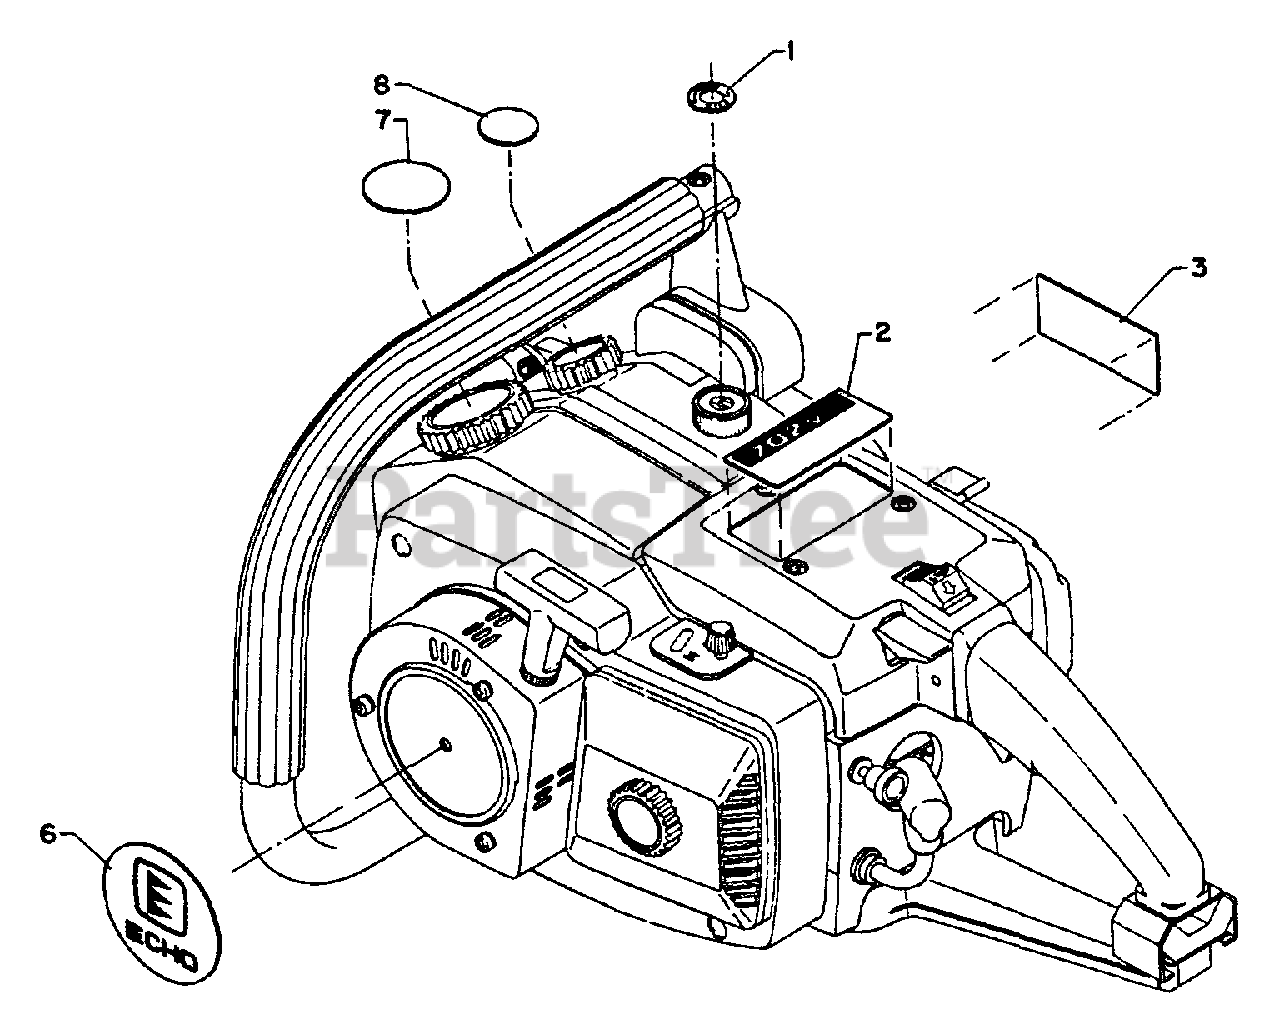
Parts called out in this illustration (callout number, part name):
1	LABEL - CAUTION
2	LABEL - MODEL
3	LABEL - ECHO
6	LABEL
7	LABEL - FUEL MIX
8	LABEL - CHAIN OIL
